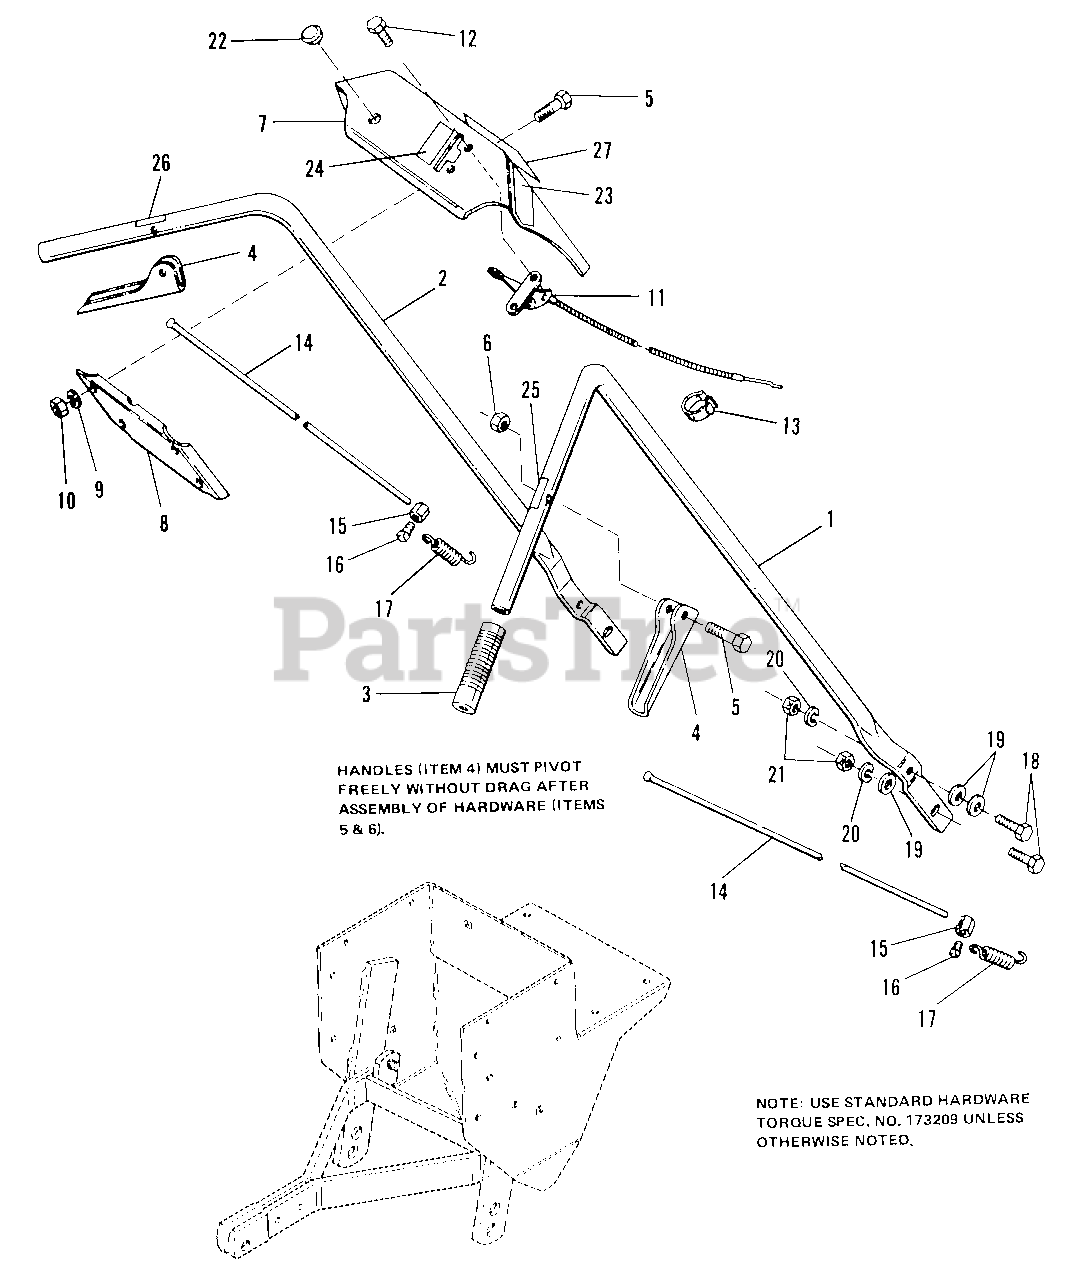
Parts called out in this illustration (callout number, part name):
1	HANDLE, R.H.
2	HANDLE, L.H.
4	GRIP, Clutch
5	CAPSCREW, Hex Hd., 1/4-20 x 1-1/2
6	NUT, Hex, Lock, 1/4-20
7	HOUSING ASSY, Control
8	COVER, Handle Upper
9	LOCKWASHER, Spring, 1/4
10	NUT, Hex, 1/4-20
11	CONTROL ASSY, Throttle
12	SCREW, Taptite, Wshr. Hd., Hex, 1/2-20 x 1/2
13	CLIP, Spring
14	ROD, Control
15	CLAMP, Wire
16	SETSCREW, Sq. Hd., Cup Pt., #10-24 x 5/8
17	SPRING
18	CAPSCREW, Hex Hd., 3/8-16 x 1-1/4
19	WASHER, Plain, 3/8
20	LOCKWASHER, Spring, 3/8
21	NUT, Hex, 3/8-16
22	BUTTON, Plug
23	DECAL, Stripe
24	DECAL, Throttle
25	DECAL, Forward
26	DECAL, Reverse
27	DECAL, Simplicity
